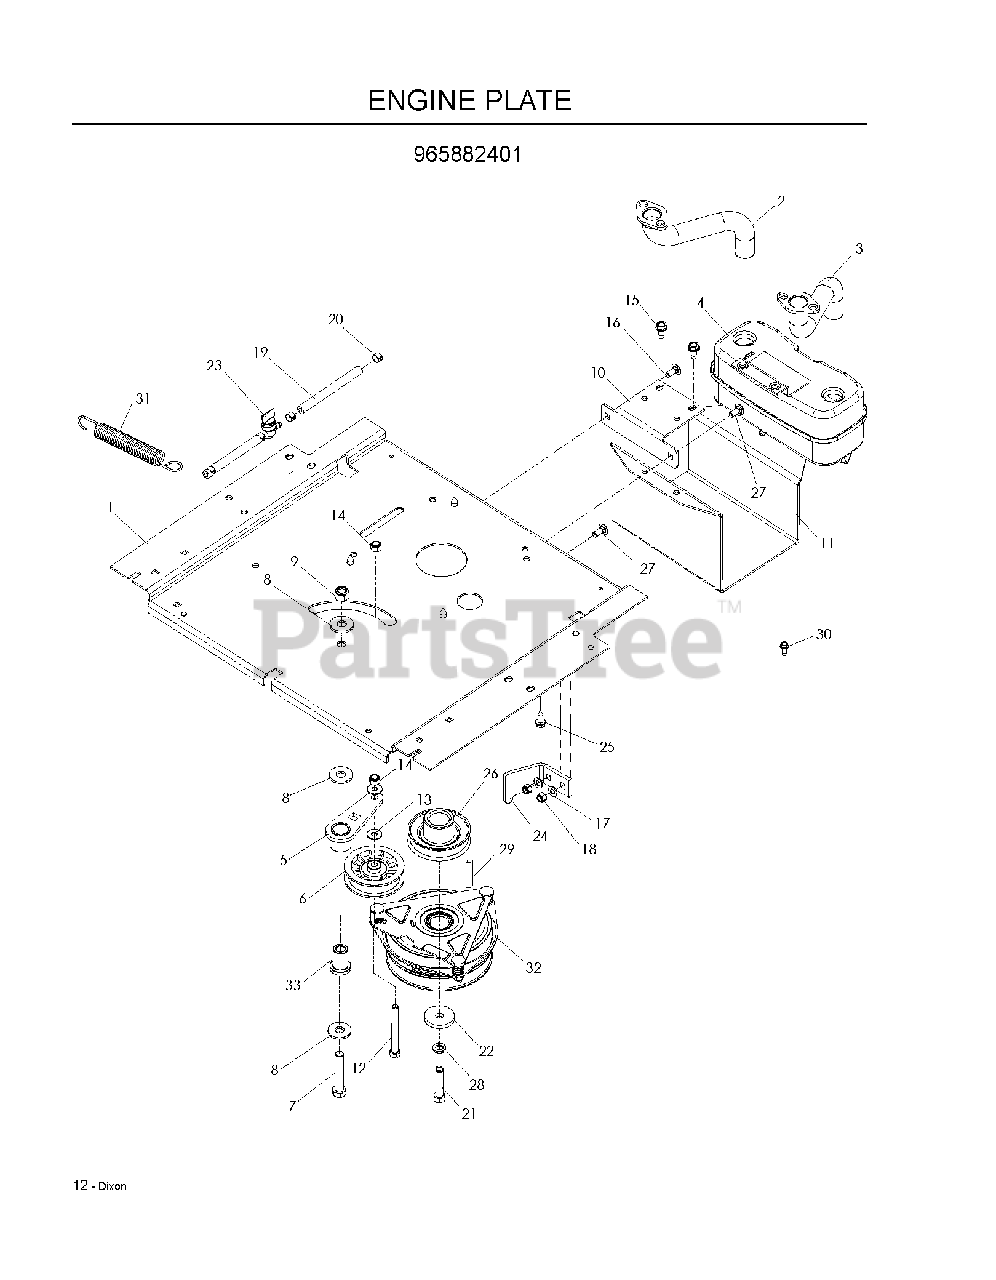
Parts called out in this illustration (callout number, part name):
1	PLATE ENGINE, BLACK
2	RP.PIPE-EXHAUST LH
3	RP.PIPE-EXHAUST RH
4	MUFFLER ASM TWIN
5	IDLER ARM WELDMENT
6	PULLEY, IDLER
7	HCS 1/2C X 2 3/4
8	WASH USS FLAT 1/2
9	NUT 1/2-13 HEX NYLOC ZD
10	BRACKET, MUFFLER, BLACK
11	GUARD, MUFFLER, BLACK
12	HCS 3/8-16X3 1/2 GR5
13	WASHER 5/16 FLAT
14	NUT 3/8-16 NYLOC
15	BOLT 5/16-18 X 3/4
16	BOLT 5/16C X 3/4" CARRIAGE
17	FLAT WASHER 5/16 SAE
18	NUT 5/16 NYLOC
19	FUEL LINE 5"
20	HOSE CLAMP
21	HCS 7/16-20 X 2 G8 ZN
22	SPINDLE WASHER
23	FUEL VALVE
24	STOP, CLUTCH OGURA BLK
25	HHFS 3/8-16 X 1.0 THD FORMING
26	PULLEY, DRIVE
27	RHSNB 5/16C X 1
28	WASHER 7/16 LOCK
29	KEY 1/4 SQ X 2
30	SCREW 1/4 X 5/8
31	SPRING, DECK DRIVE
32	CLUTCH, 150 FT/LBS
33	PIVOT, IDLER
